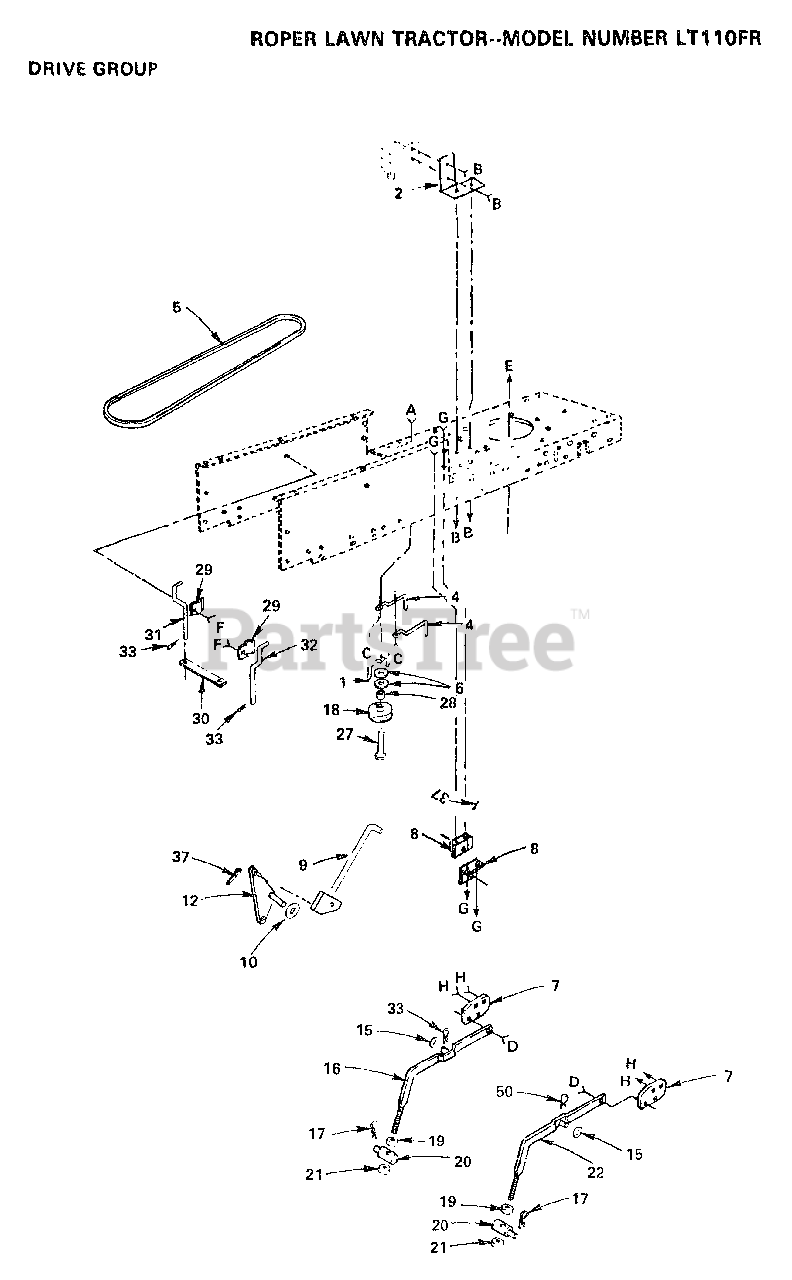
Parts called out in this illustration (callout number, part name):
1	BELT KEEPER LT
2	BRACKET LT
4	"KEEPER,BLT ENG LT"
6	WASHER
7	"BRACKET, SUSPE T"
8	"BRKT,BELLCRAN T"
9	ROD ASSEM YT
10	WASHER
12	"T, BELLCRANK"
15	WASHER
17	SPRING H
19	NUT
21	NUT LTV
27	BOLT
28	SPACER T
29	CLAMP LT
37	COTTER PIN
